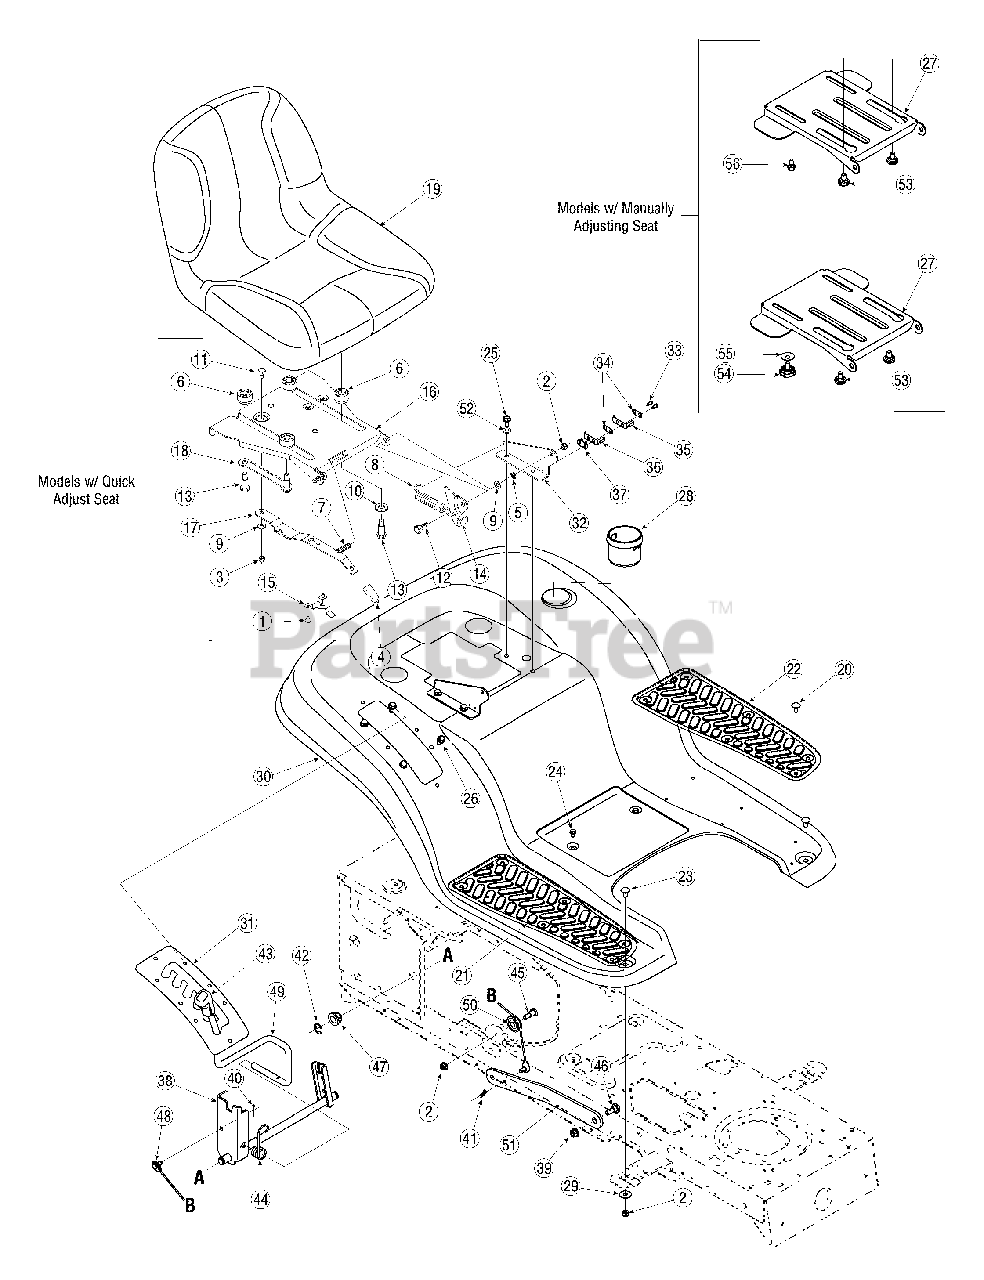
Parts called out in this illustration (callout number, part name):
1	Screw, #10-16 x.375
2	Nut, Flange Lock, 5/16-18, Gr F, Nylon
3	Nut, Flange Lock, 1/4-20
4	Seat Adjuster Grip
5	Nut, Speed,.3125 ID
6	Spacer
7	Compression Spring,.41 x 1.5
8	Spring, Extension,.84 Dia. x 4.6
9	Wash, Flat,.344 x.688 x.065
10	Wash, Flat,.531x 1.062 x.134
11	Screw, Shoulder,.340 x.285,1/4-20
12	Screw, Shoulder,.437 x.268, 5/16-18
13	Screw, Shoulder,.50 x.925, 3/8-16
14	Seat Bracket, Lift
15	Seat Stop
18	Seat Adjustment Selector
19	Medium Back Seat
20	Ratchet Clip
21	RH Foot Pad, Rubber
22	LH Foot Pad, Rubber
23	Bolt, Carriage, 5/16-18,.62, Gr1
24	Screw, 1/4-20, 0.500
25	Screw, 5/16-12, 0.750
26	Screw, 5/16-18 x.750
28	Cup Holder
29	Washer, Flat,.344 x 1.0 x.063
33	Screw, #8-18 x.50
34	Plate, Insulator
35	Spring Switch, Outer
36	Spring Switch, Inner
37	Plate, Insulator Boss
39	Nut, Flange Lock, 3/8-16, Gr F, Nylon
40	Pin, Cotter,.072 Dia. x 1.13
41	Pin, Cotter, 3/32, 1.0
42	Ring, E Type,.625 Dia.
43	Grip, Handle, 1/2
44	Spring, Torsion
45	Screw, 5/16-18 x.620 Gr2
46	Screw, Shld,.625 x.165, 3/8-16
47	Bearing, Hex Flange
48	Cable, Lift, 16.16
49	Handle, Lift
50	Pulley, Roller
52	Lock Washer, 5/16
53	Shoulder Screw
54	Knob, 3/8-16
55	Flat Washer,.406 x 1.00 x.030
56	Hex Head Washer Screw, 3/8-16 x.625
